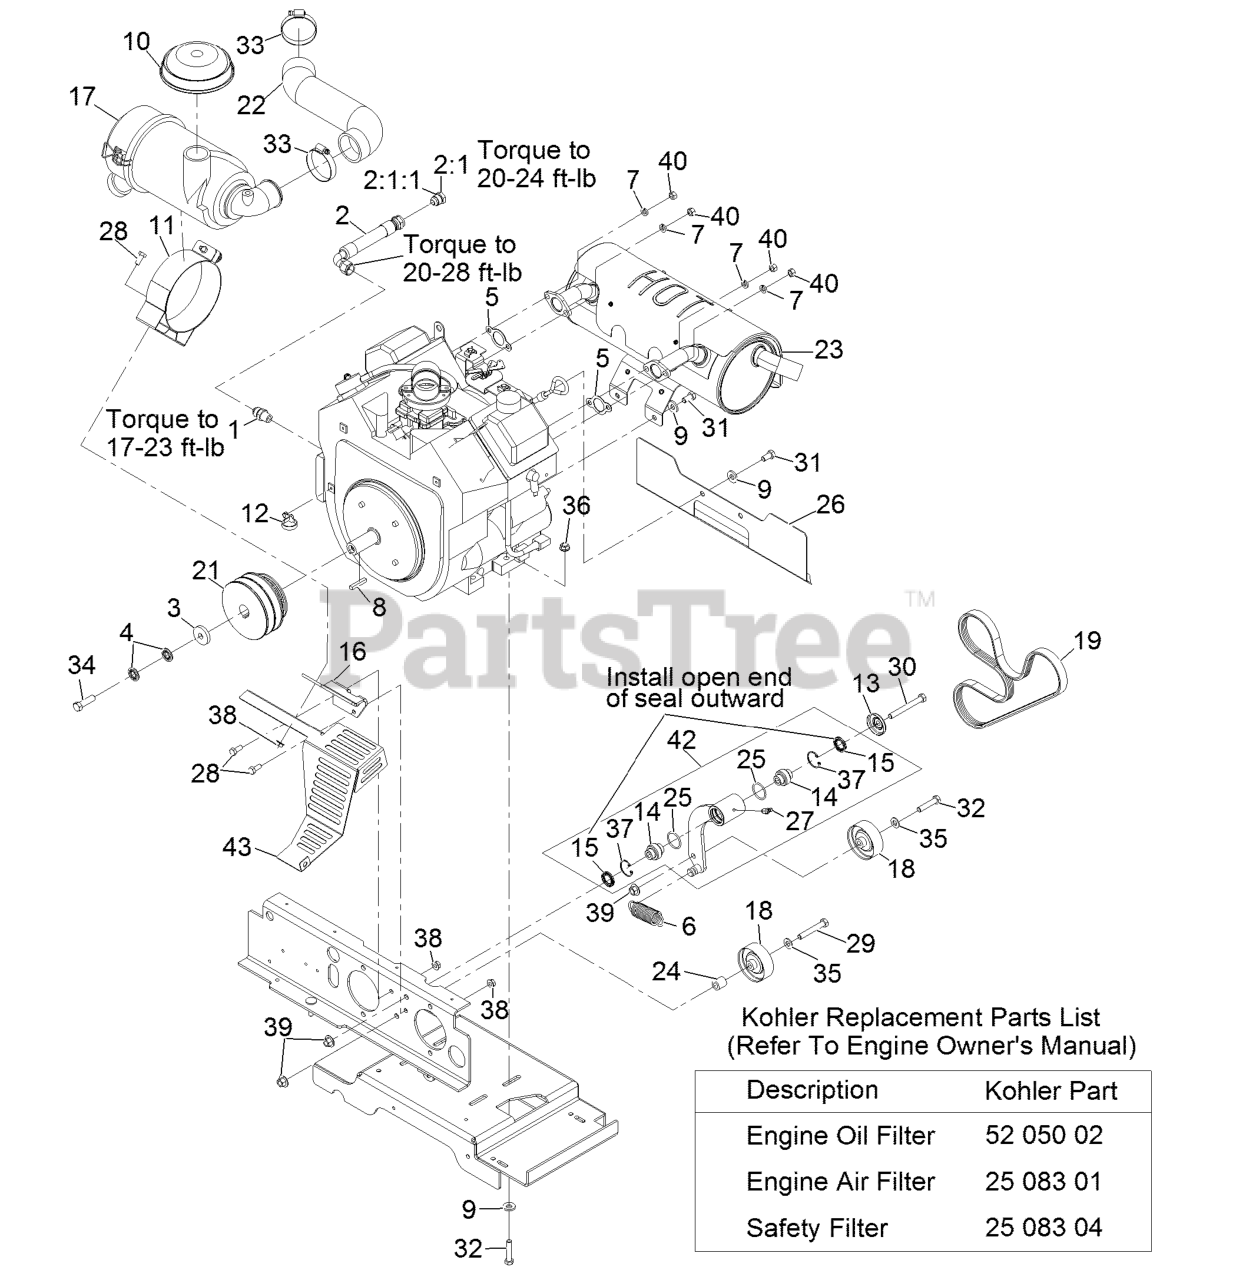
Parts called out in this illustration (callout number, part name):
1	FITTING-STRAIGHT
2	OIL DRAIN HOSE ASM
2:1	PLUG-HH
2:1:1	O-RING
3	WASHER-CLUTCH
4	WASHER-SPRING
6	SPRING-IDLER
7	WASHER-LOCK
8	KEY-SQUARE
9	WASHER-BELLEVILLE
10	HOOD-CLEANER, 2" AIR INTA
11	BRACKET-FILTER, AIR
12	Tie-Cable
13	GUARD-TOP
14	BEARING-SPHERICAL
15	SEAL-LIP, SINGLE
16	BRACKET-FILTER, AIR
17	AIR CLEANER CANISTER ASM
19	BELT-V
22	HOSE-AIR INTAKE
24	SPACER-MOUNTING, STEERING
26	SHIELD-EXHAUST
27	FITTING-LUBE, 45 DEG
28	SCREW-HH
29	BOLT-CARR
30	SCREW-HH
31	SCREW-HH
32	SCREW-HH
33	CLAMP-HOSE
34	SCREW-HH
35	WASHER-FLAT
36	NUT-HHF, WHIZ
37	RING-SNAP
39	NUT-FLANGE
40	NUT-HEX
42	IDLER ASM
43	SHIELD-HEAT
